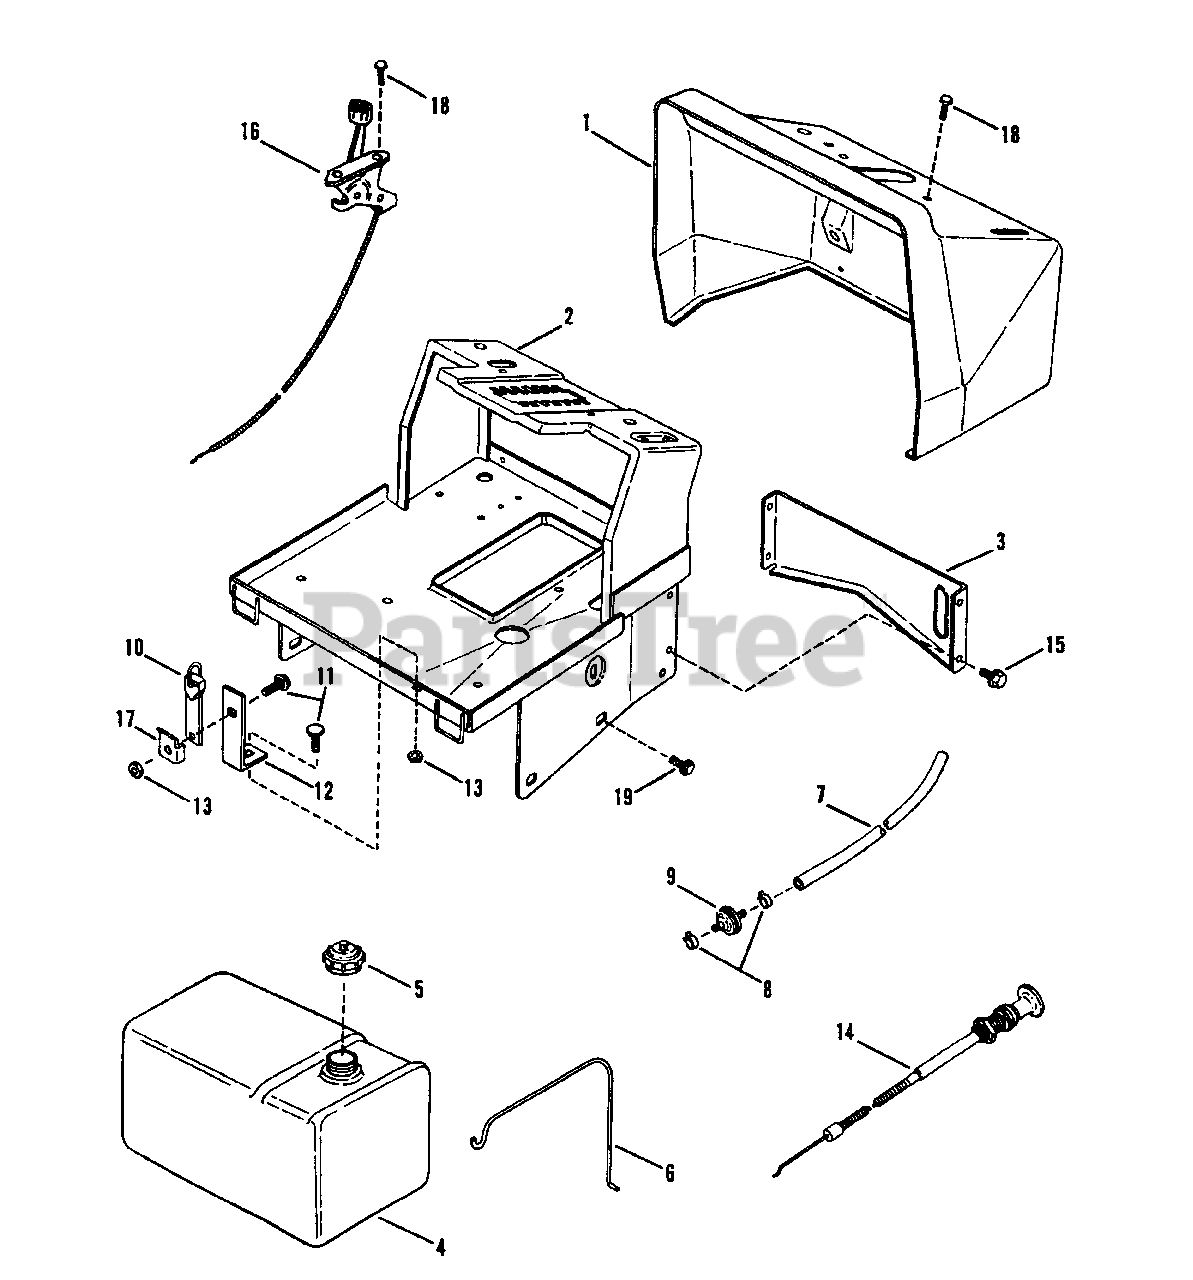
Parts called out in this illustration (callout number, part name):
1	PANEL, Dash
2	PEDESTAL
3	BRACKET, Lower Dash
4	TANK, Fuel
5	CAP, Fuel Tank Filler
6	HOLD-DOWN, Fuel Tank
7	LINE, Fuel (14-1/2" Long)
8	CLAMP, Fuel Line
9	FILTER, Fuel (In-Line)
10	STRAP, Tank Hold Down
11	BOLT, 1/4-20 x 5/8 Flat Head Carriage, Grade 2
12	BRACKET, Fuel Tank
13	NUT, 1/4-20 Hex Flange Lock, Grade 5
14	CONTROL, Choke Cable (29")
15	SCREW, 5/16-18 x 1/2" Hex Washer Face Self-Tap
16	CONTROL, Throttle - B&S 30.0"
16	CONTROL, Throttle - Kohler 30.85"
17	CLIP, Hood Retainer
18	SCREW, #10-24 x 1/2" Hex Washer Face Self-Tap
19	SCREW, 5/16-18 x 5/8" Hex Washer Face Self-Tap
